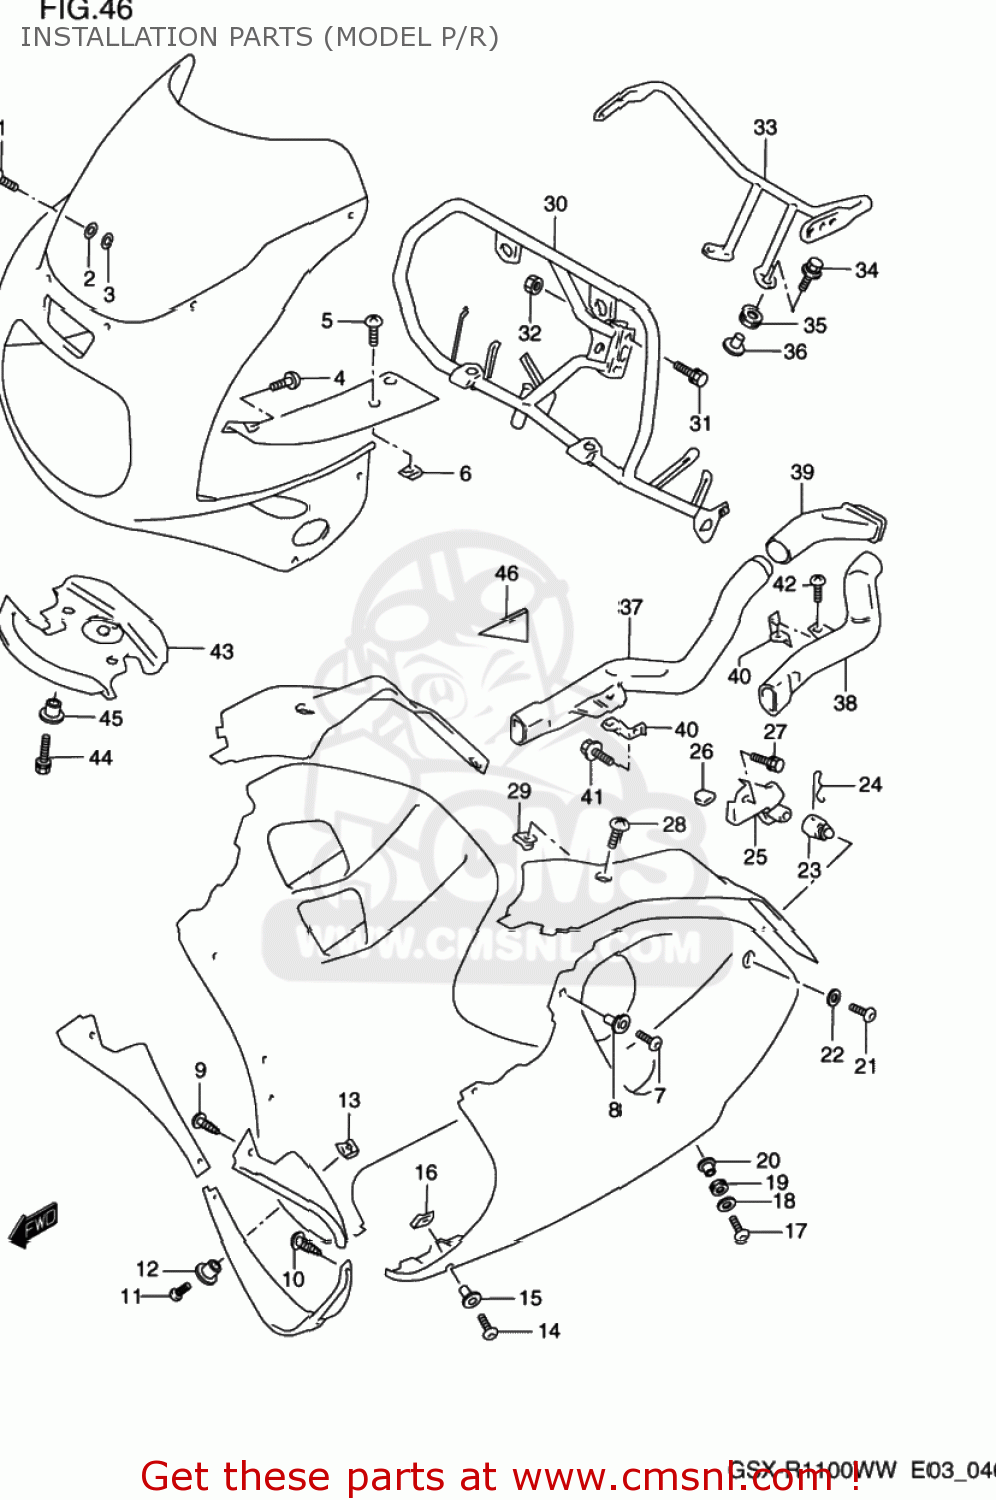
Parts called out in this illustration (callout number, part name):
1	PIN,WINDSCREEN
2	CUSHION
3	NUT
4	SCREW 5X12
5	SCREW
6	NUT
7	SCREW(5X18)
8	WASHER(5.2X14X1.5)
9	SCREW 5X10
10	SCREW 5X10
11	SCREW(5X18)
12	WASHER(5.2X14X1.5)
13	NUT,HEADLAMP HOUSING,UPPER
14	SCREW(5X18)
15	WASHER(5.2X14X1.5)
16	NUT,HEADLAMP HOUSING,UPPER
17	SCREW(6X25)
18	WASHER(6.5X18X1)
19	CUSHION
20	WASHER
21	SCREW(6X20)
22	WASHER
23	PLUG,UNDER COWL FTG,CTR
24	PIN,UNDER COWLING FITTING PIPE
25	BRACE,UNDER COWLING UPR,R
26	CUSHION,UPR BRACE
27	BOLT
28	SCREW
29	NUT
30	BRACE,COWLING
31	BOLT
32	NUT
33	BRACE,RR VIEW MIRRORR
34	BOLT 6X20
35	CUSHION
36	WASHER
37	PIPE,AIR INTAKE,FRONT
38	PIPE,AIR INTAKE,FRONT
39	PIPE,AIR INTAKE,REAR,RIGHT
40	BRACKET,AIR INTAKE,LEFT
41	BOLT
42	SCREW 6X12
43	COVER,COWLING FR LWR
44	BOLT
45	WASHER
46	CUSHION,AIR INTAKE PROTECTOR,R
